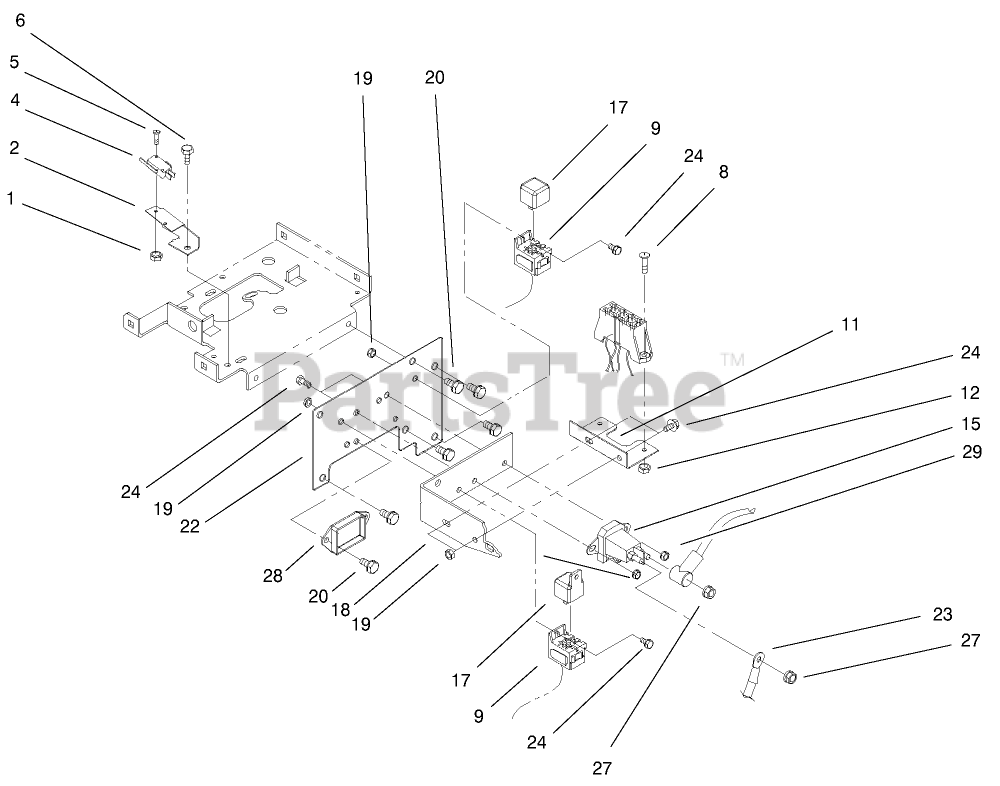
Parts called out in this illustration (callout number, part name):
1	NUT-HEX, NYL INS
4	SWITCH
5	SCREW-PPH
6	SCREW-HWH
8	SCREW-PAN
9	HARNESS-WIRE,KOHLER,12HP
9	HARNESS-WIRE,KOHLER,14HP
11	FUSE HOLDER
12	NUT-LOCK, NI
15	SOLENOID
17	RELAY
18	BRACKET-BELT
19	NUT-LOCK, NI
20	SCREW-HWHTF
22	PLATE-HOODSTAND, FRONT
23	CABLE-BATTERY, POSITIVE
24	SCREW-HHF
27	NUT-KEPS
28	MODULE
29	NUT-KEPS
